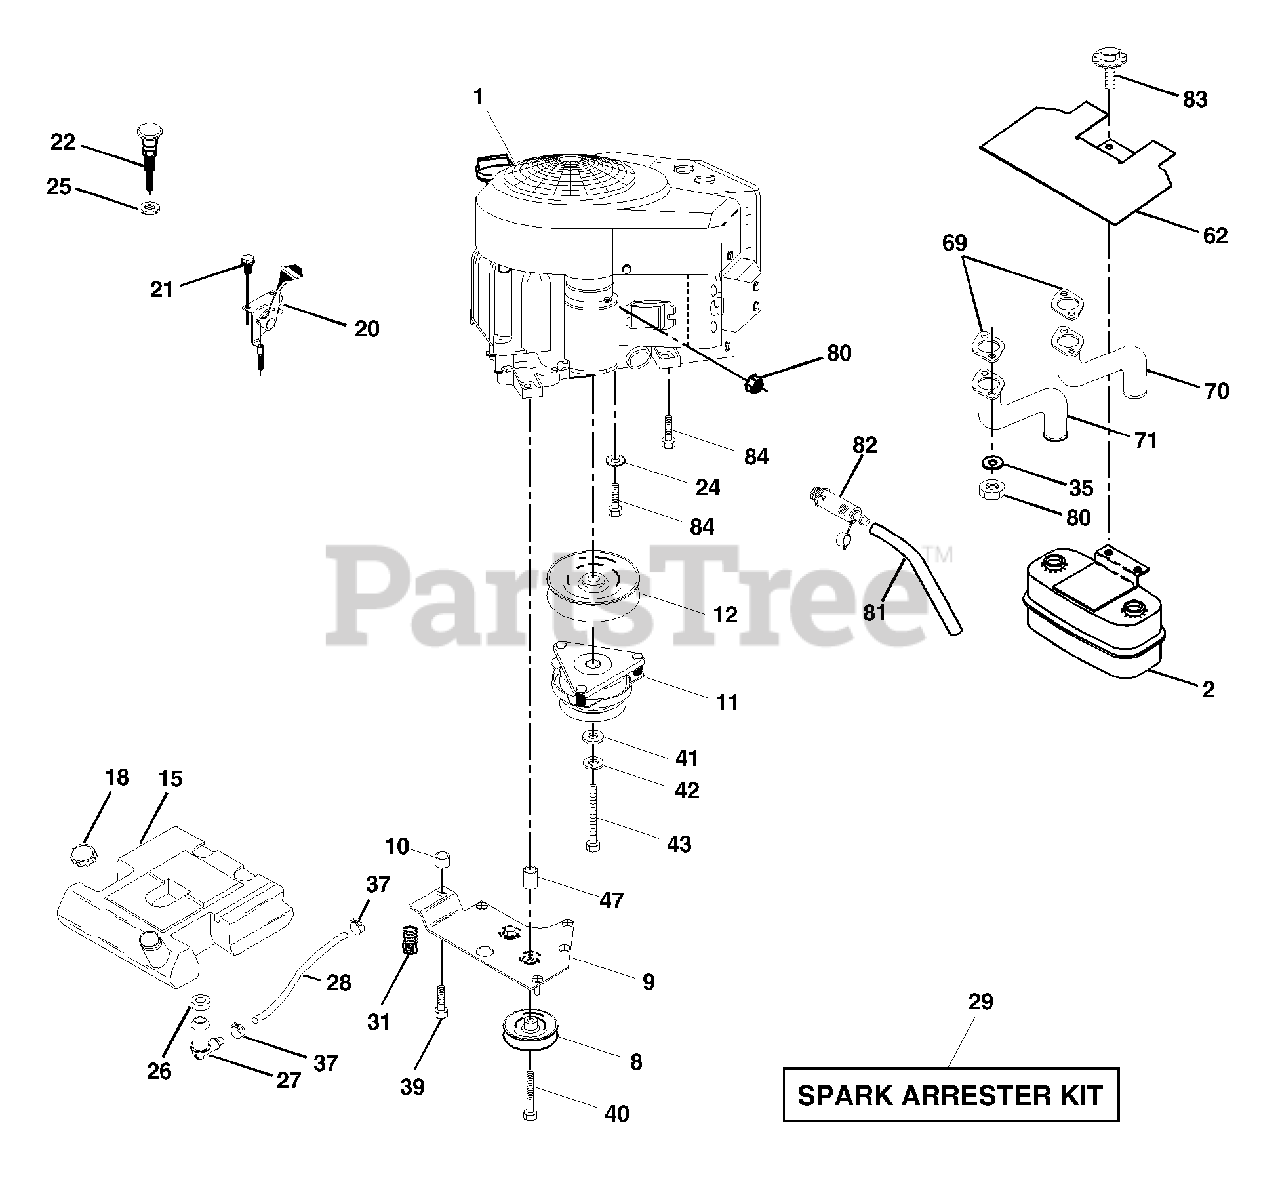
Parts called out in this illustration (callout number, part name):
2	Muffl er Side
8	Pulley V-Idler
9	Keeper Asm. Belt Engine VGT
11	Clutch Electric
12	Pulley Engine VGT Elect Clutch
18	Cap Fuel
20	Control Throttle
21	Screw HWHD Hi-Lo #13-16 x 3/4
22	Control Choke
24	Washer Ext Tooth 3/8
25	Nut Keps 3/8-24 Unf
26	Bushing
27	Stem Tank Fuel
28	Fuel Line
29	Spark Arrester Kit
31	Clip Push-In Hinged
37	Clamp Hose
39	Screw TT 3/8-16 x 2-1/4 Unc
40	Screw TT 3/8-16 x 4 Unc
41	Washer 1-1/2 OD x 15/32 ID x .250
42	Washer Lock 7/16
43	Bolt Hex 7/16-20 X 3.75 Gr. 5
62	Shield Heat Muffl er
69	Gasket
70	Tube Exhaust LH
71	Tube Exhaust RH
80	Nut Flange M8-1.25
81	Tube Drain Oil Easy
82	Valve Oil Drain
83	Bolt 5/16-18 Unc x 1-3/4 W/Sems
84	Screw 3/8-16 x 1-1/2
